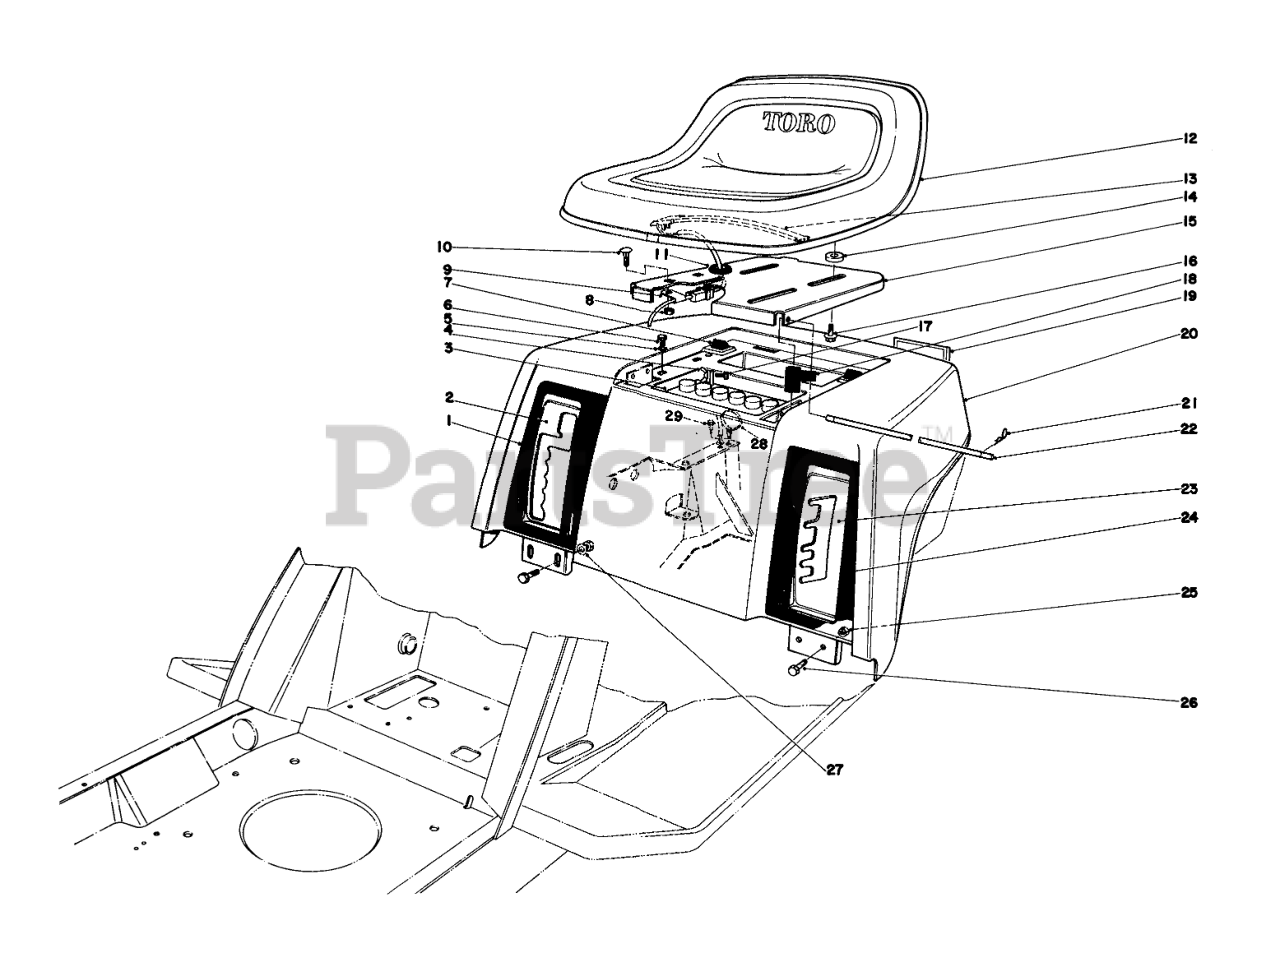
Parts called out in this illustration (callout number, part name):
1	Decal-Transmission
2	DETENT PLATE B
3	Battery
4	NUT-WING
5	WASHER
6	SCREW-HWHTF
7	SEAT BUMPER
8	NUT-KEPS
9	CLAMP
10	SCREW-CARR
11	GROMMET
13	SWITCH-SEAT
14	Spacer
15	SEAT SUPPORT R
16	SCREW-HHF
17	SCREW-HH
18	BOOT-TERMINAL
19	REFLECTOR
20	Rear Body
21	PIN-COTTER
22	PIVOT-SEAT
23	Quadrant Height of Cut
24	Decal-Height-of-Cut
25	NUT-LOCK, CONE
26	SCREW-HH
27	WASHER-PLAIN
28	Push Mount Tie
29	SCREW-HWHTF
